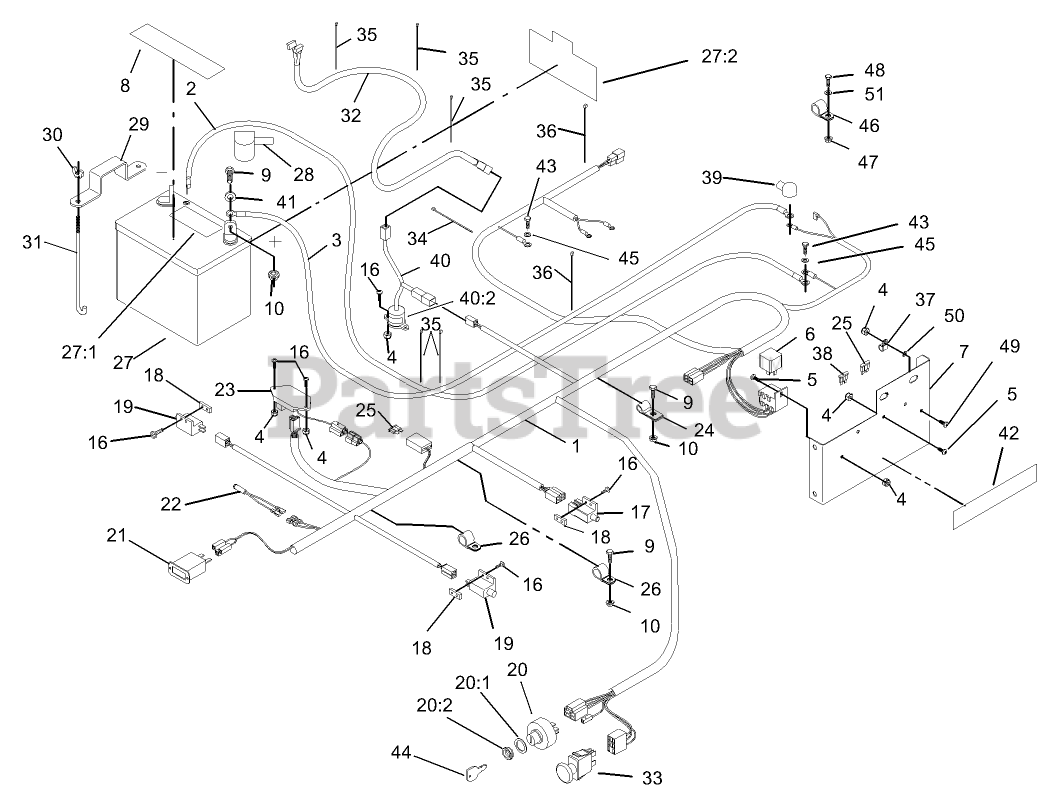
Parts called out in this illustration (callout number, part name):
1	HARNESS-WIRE
2	WIRE-GROUND
3	WIRE-BATTERY, POSITIVE
4	NUT-LOCK, NI
7	PANEL-MOUNT, FUSE
8	Decal-Warning, Battery
9	SCREW-HH
10	NUT-HF
16	SCREW-PPH
17	SWITCH
18	PLATE-TAPPED
19	SWITCH-OPEN, NORMALLY
20	Key Switch ASM
20:1	WASHER-TOOTH, INTERNAL
20:2	NUT-HH
21	METER-HOUR
22	INDICATOR-LED, RED
23	MODULE-DELAY, SEAT
24	CLIP-LOOM
25	FUSE-BLADE TYPE, 20 AMP
27	BATTERY
27:1	Decal-Battery
27:2	Decal-Battery
28	INSULATOR-BATTERY
29	STRAP-HOLDDOWN
30	WINGNUT
31	BOLT-HOLDDOWN
32	HARNESS-WIRING, SEAT
33	SWITCH-DELTA
34	TIE-CABLE
35	TIE-PLASTIC
36	TIE-PLASTIC
37	CLIP-LOOM
38	FUSE-BLADE TYPE, 10 AMP
39	INSULATOR-SOLENOID
40	TILT SWITCH ASM
40:2	DECAL-SWITCH, MERCURY
41	WASHER-FLAT
42	DECAL-RELAY / FUSE
43	SCREW-HH
44	KEY-IGNITION
45	WASHER-PLAIN
46	CLIP-LOOM
47	NUT-LOCK, NI
48	SCREW-HH
49	SCREW-HH
50	WASHER-FLAT
51	WASHER-FLAT
